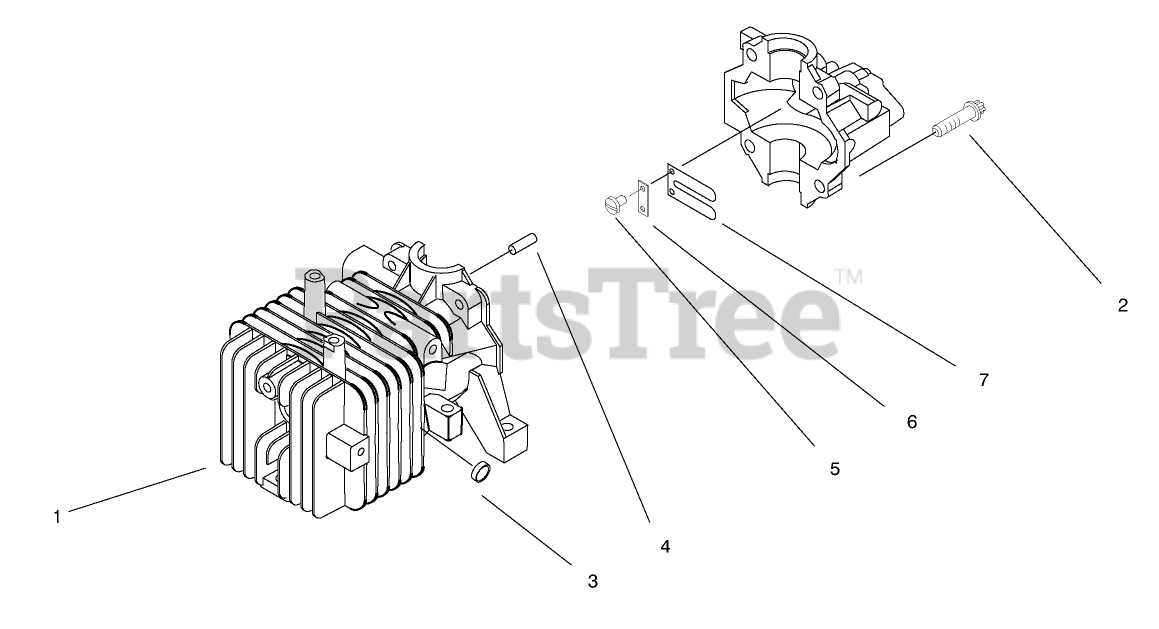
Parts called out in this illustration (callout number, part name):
1	CYL C/CASE V
2	SCREW - EXT TORX HD
3	PLUG-CORE VF
4	DOWEL XEV
5	SCREW-HH
6	PLATE-BACKUP, REED
